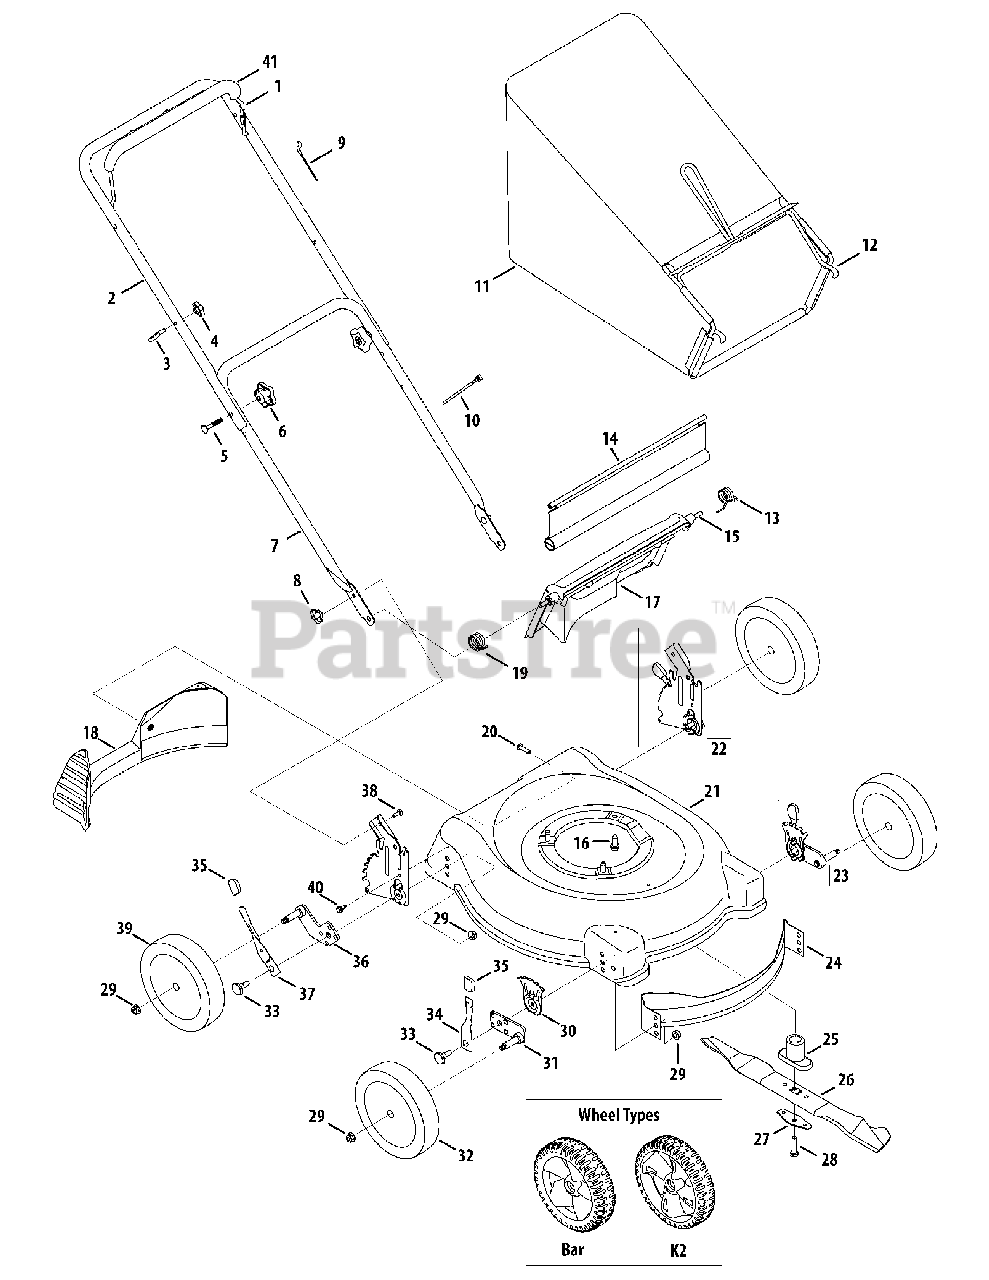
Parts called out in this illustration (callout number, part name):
3	Rope Guide
4	Wing Nut, 1/4-20
5	Carriage Bolt, 5/16-18 x 2
6	Hand Star Knob
8	Wing Nut, 1/4-20
9	Control Cable - 37.25"
9	Control Cable - 40"
9	Control Cable - 40.5"
9	Control Cable - 53"
10	Cable Tie
11	Grass Bag
13	Torsion Spring LH
14	Trailshield
15	Rear Door Pivot Rod
16	TT Screw, 3/8-16 x 1
17	Rear Discharge Door
18	Rear Baffle
19	Torsion Spring RH
20	Screw, 1/4-15 x 1.00
22	Handle Bracket Assy - RH
22	Handle Bracket Assy - LH
23	Ht. Adj. Assy. Frt - LH (8" Wheel)
23	Ht. Adj. Assy. Frt - RH (8" Wheel)
23	Ht. Adj. Assy. Frt - LH (7" Wheel)
23	Ht. Adj. Assy. Frt - RH (7" Wheel)
24	Front Baffle
25	Blade Adapter, #6 x 2.15
25	Blade Adapter, 25mm x 2.15
26	Standard Blade
26	Mulch Blade
27	Blade Bell Support
28	Screw, 3/8-24 x 2.50 (w/ #6 x 2.15 w/Star Blade Adapter)
28	Screw, 3/8-24 x 1.50 (w/25mm Blade Adapter)
29	Flange Lock Nut, 3/8-16
30	Height Adjustment Plate
31	Pivot Arm Assy RH (7" wheel)
31	Pivot Arm Assy LH (7" wheel)
31	Pivot Arm Assy LH (8" wheel)
31	Pivot Arm Assy RH (8" wheel)
32	Wheel, 7 x 1.8, Spoke Bar
32	Wheel, 7 x 1.8, K2 Bar
33	Shoulder Screw
34	Spring Lever
35	Height Adjustment Knob
36	Pivot Arm Assembly - RH
36	Pivot Arm Assembly - LH
37	Spring Lever
38	Carriage Bolt, 1/4-20
39	Wheel, 8 x 1.8, Spoke Bar
39	Wheel, 8 x 1.8, K2 Bar
40	Screw, 1/4-20 x .625
41	Bail Cover
